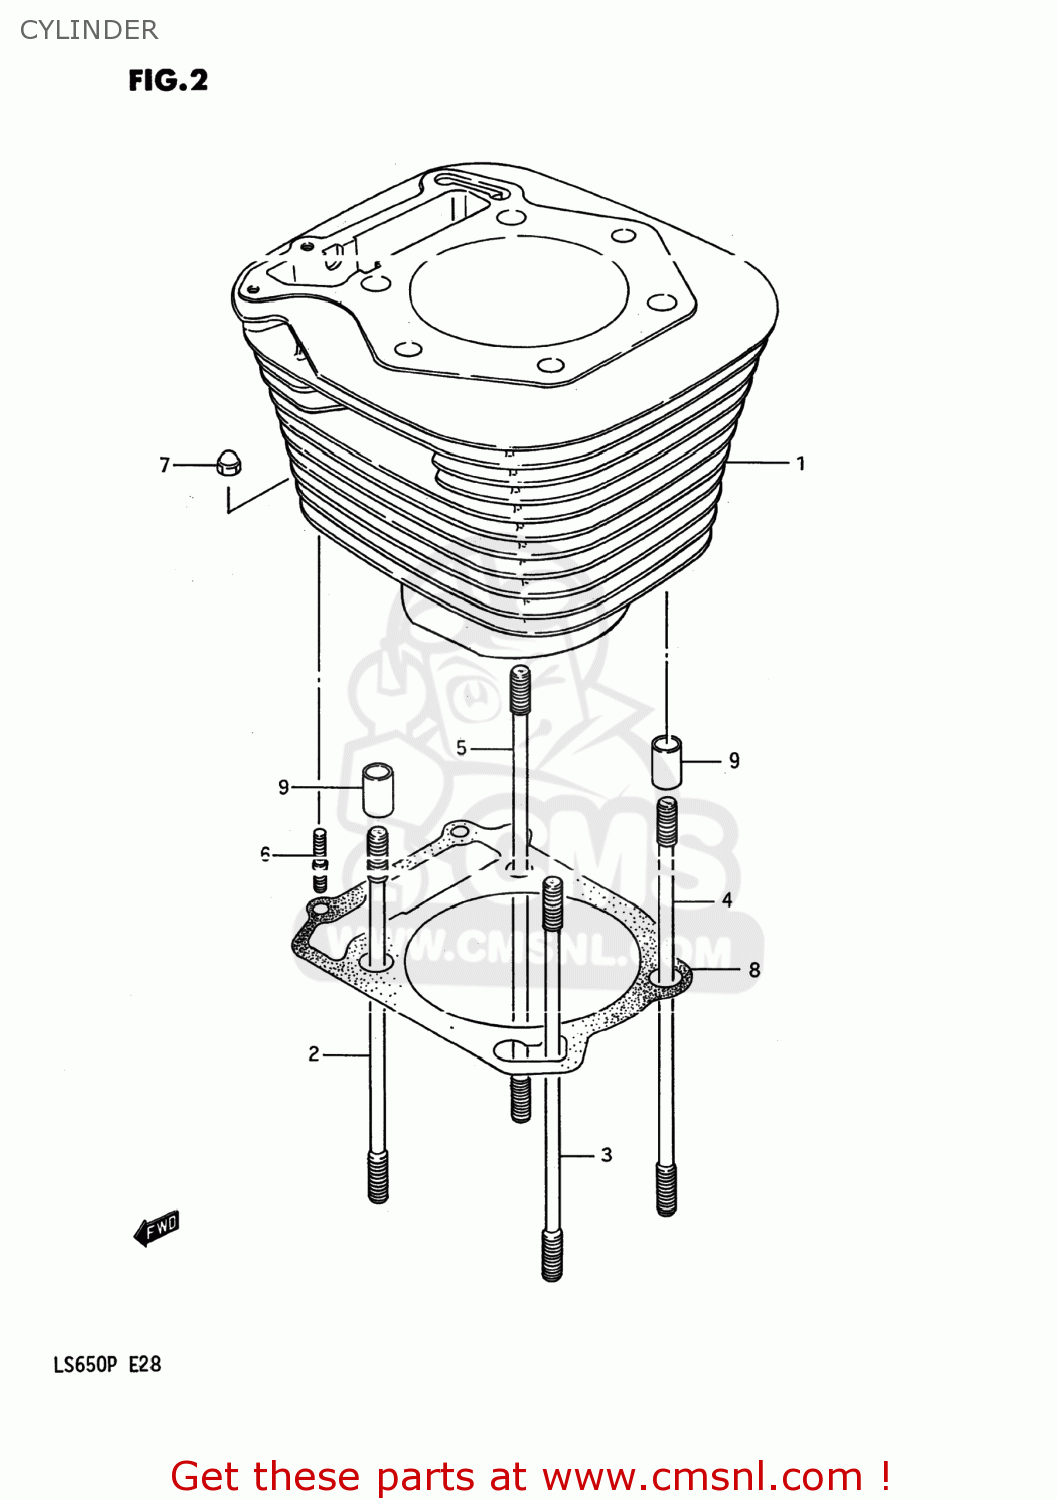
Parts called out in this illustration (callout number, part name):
1	CYLINDER
2	BOLT,STUD
3	BOLT,STUD
4	BOLT,STUD
5	BOLT,STUD
6	STUD 6X20
7	NUT
8	GASKET,CYLINDER (NAS)
9	PIN
